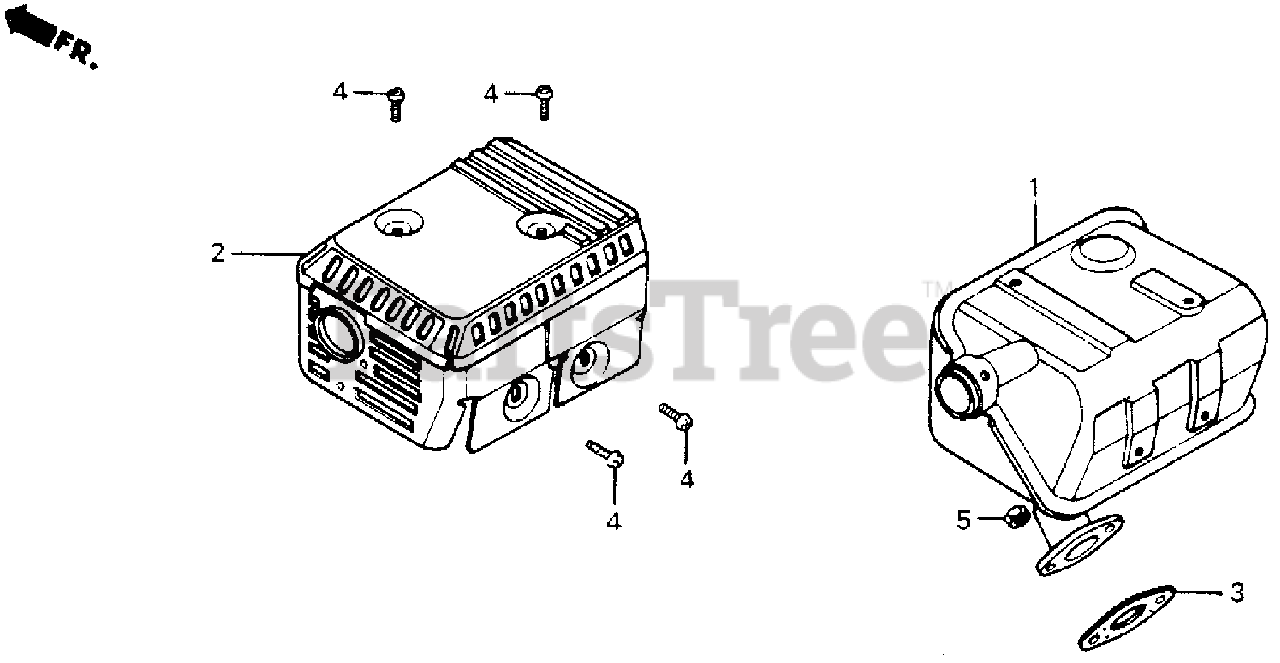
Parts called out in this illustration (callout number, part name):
1	MUFFLER
2	PROTECTOR, MUFFLER
3	GASKET, MUFFLER
4	SCREW, TAPPING (5X8)
5	NUT, HEX. (8MM)
